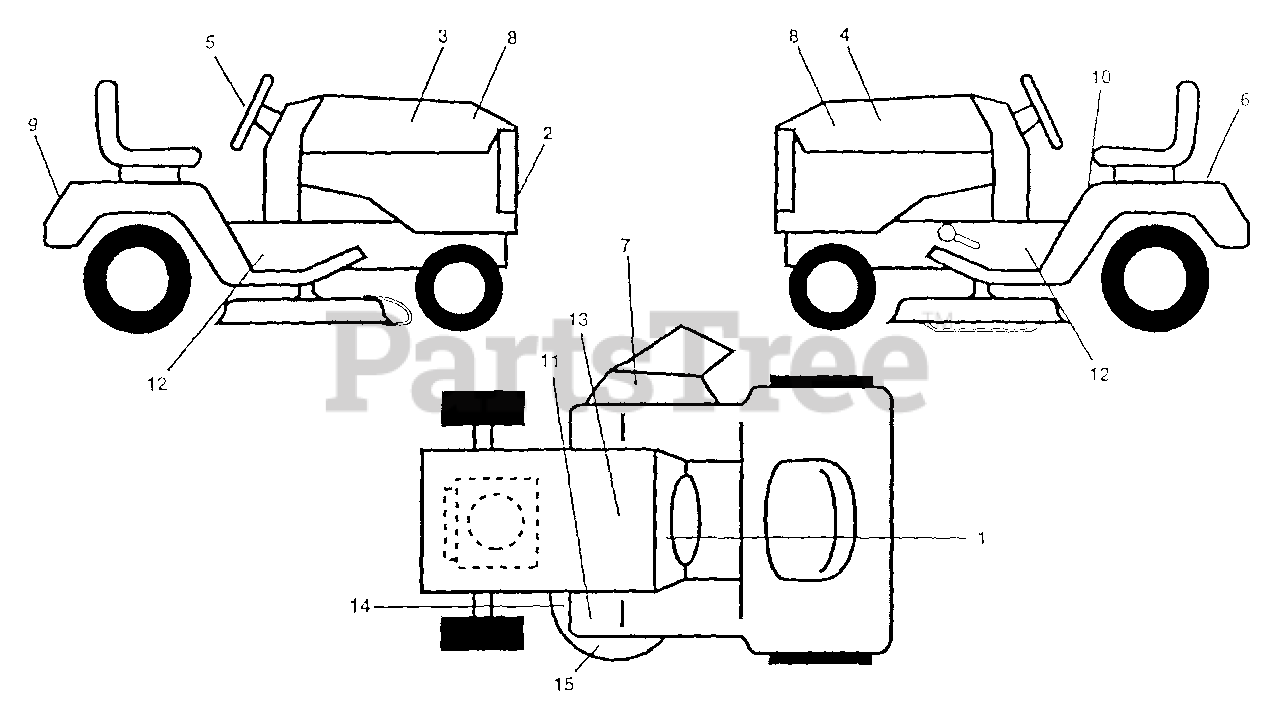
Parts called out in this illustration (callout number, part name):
1	Decal, Operating Instruction
2	Decal, Grille
3	Decal, Hood, RH
4	Decal, Hood, LH
5	Decal, Insert Strg. Wheel
6	Decal, Cust Assist
7	Decal, Warning Multi-Language
8	Decal, Domed Poulan Pro
9	Decal, Fender (AYP part number)
10	Decal, Danger
11	Decal, Clutch/Brake
12	Decal, Chassis
13	Decal, Bat Dan/Poi P/L Sym
14	Decal, V-Belt Schematic (AYP part number)
15	Decal, Mower Enviro White
